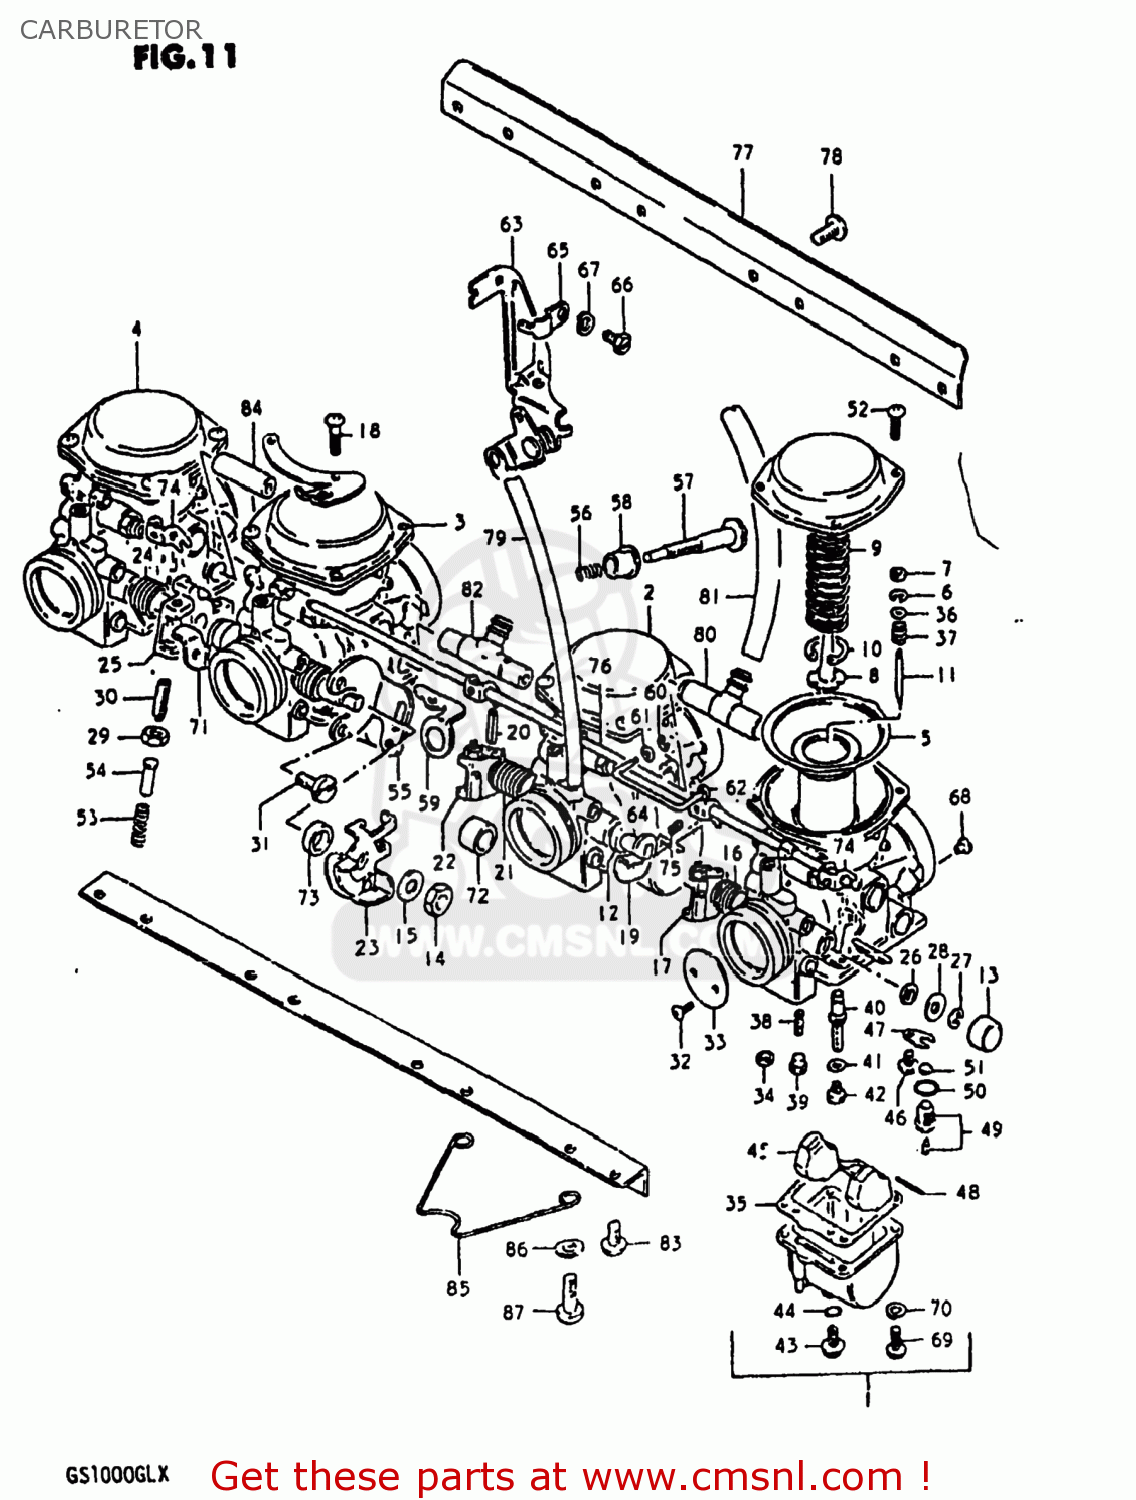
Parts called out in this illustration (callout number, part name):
1	CARBURETOR ASSEMBLY
2	CARBURETOR ASSEMBLY,NO.2
3	CARBURETOR ASSEMBLY
4	CARBURETOR ASSEMBLY
5	DIAPHRAGM ASSEMBLY
6	CLIP,NEEDLE
7	RING
8	HOLDER,GUIDE
9	SPRING
10	E RING
11	NEEDLE JET
12	GASKET
13	CAP
14	NUT
15	WASHER
16	SPRING,THROTTLE SHAFT
17	SHAFT,THROTTLE
18	SCREW
19	SHAFT,THROTTLE
20	PIN,THROTTLE SHAFT
21	SPRING,THROTTLE SHAFT
22	LEVER,THROTTLE SHAFT
23	LEVER ASSEMBLY,THROTTLE
24	SPRING,THROTTLE SHAFT
25	SHAFT,THROTTLE
26	SEAL
27	E RING
28	GASKET,THROTTLE SHAFT (NAS)
29	NUT
30	SCREW
31	SCREW
32	SCREW
33	VALVE,THROTTLE
34	GASKET (NAS)
35	GASKET,FLOAT CHAMBER (NAS)
36	WASHER
37	SPRING
38	JET,PILOT
39	PLUG,NEEDLE JET
40	JET,NEEDLE
41	WASHER,NEEDLE NOZZLE
42	JET,MAIN(115)
43	PLUG,DRAIN
44	GASKET (NAS)
45	FLOAT
46	SCREW
47	PLATE
48	PIN,FLOAT
49	VALVE ASSEMBLY,NEEDLE
50	O RING
51	FILTER
52	SCREW
53	SPRING,THROTTLE SCREW
54	PIN,THROTTLE LEVER
55	BRACKET,THROTTLE ADJUST
56	SPRING
57	SCREW
58	BUSH
59	BRACKET,THROTTLE ADJUST
60	CAP,LEVER
61	SEAT,SPRING
62	LEVER ASSY
63	BRACKET
64	ROD,STARTER LEVER
65	BRACKET,STARTER
66	BOLT
67	LOCK WASHER
68	JET,AIR
69	SCREW
70	LOCK WASHER
71	SHAFT,THROTTLE
72	RING
73	RING
74	LEVER
75	SCREW
76	SHAFT,STARTER
77	BRACKET
78	SCREW
79	HOSE
80	NIPPLE
81	HOSE
82	NIPPLE
83	SCREW 6X12
84	NIPPLE
85	CLAMP
86	WASHER
87	SCREW
